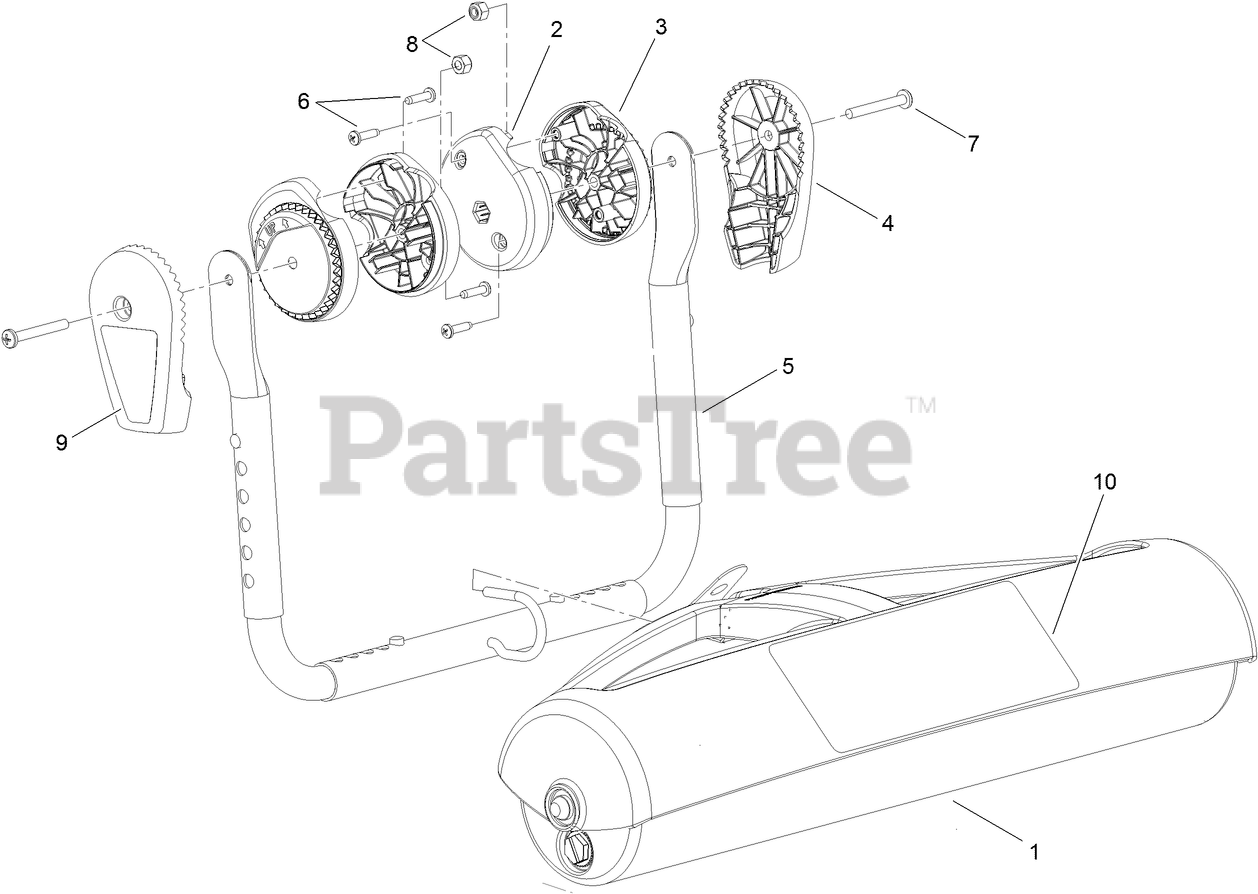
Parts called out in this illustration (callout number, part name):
1	ROLLER ASM
2	CLAMP-HANDLE, INNER
3	CLAMP-HANDLE, OUTER
4	CLAMP-ADJUSTER, ANGLE
5	TUBE ASM
6	SCREW-PPH
8	NUT-HH, NI
9	DECAL-ATTACHMENT
10	DECAL-COVER
